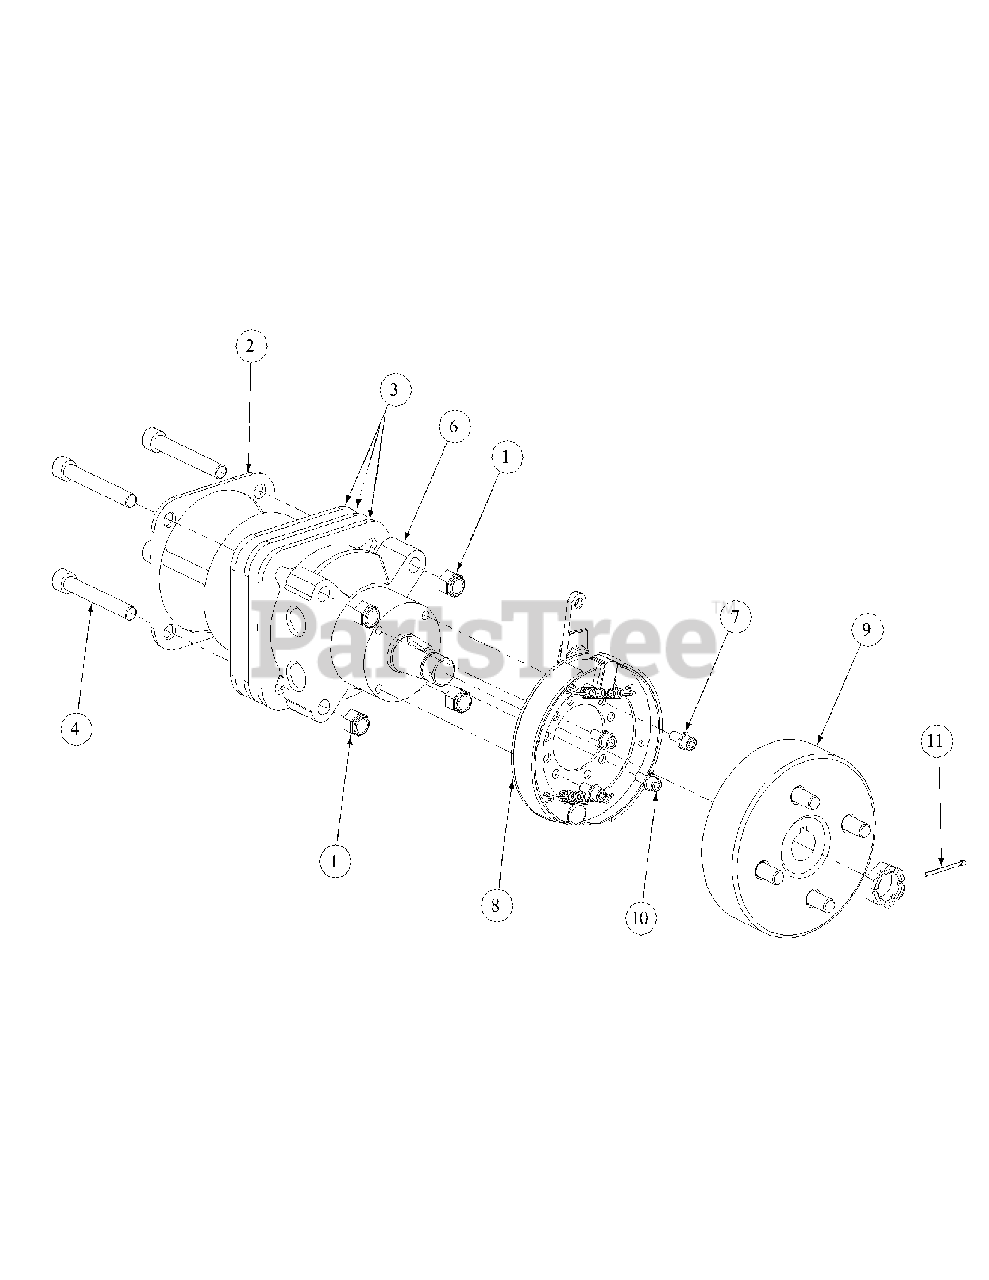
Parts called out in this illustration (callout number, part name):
1	Lock Nut, Nylon Insert, 1/2-13
2	Motor Plate
3	Motor Spacer
4	Socket Head Capscrew, 1/2-13; 3-1/2
4	Capscrew, 1/2-13 x 3.5
5	Hyd. Motor, Parker Left Hand
6	Hyd. Motor, Parker Right Hand
7	Lock Washer, 5/16
8	Brake Assembly w/Line
9	Hub and Drum Assembly w/Studs
10	Capscrew w/Socket, 5/16-18 x 3/4
11	Cotter Pin 1/8 x 1-1/2
